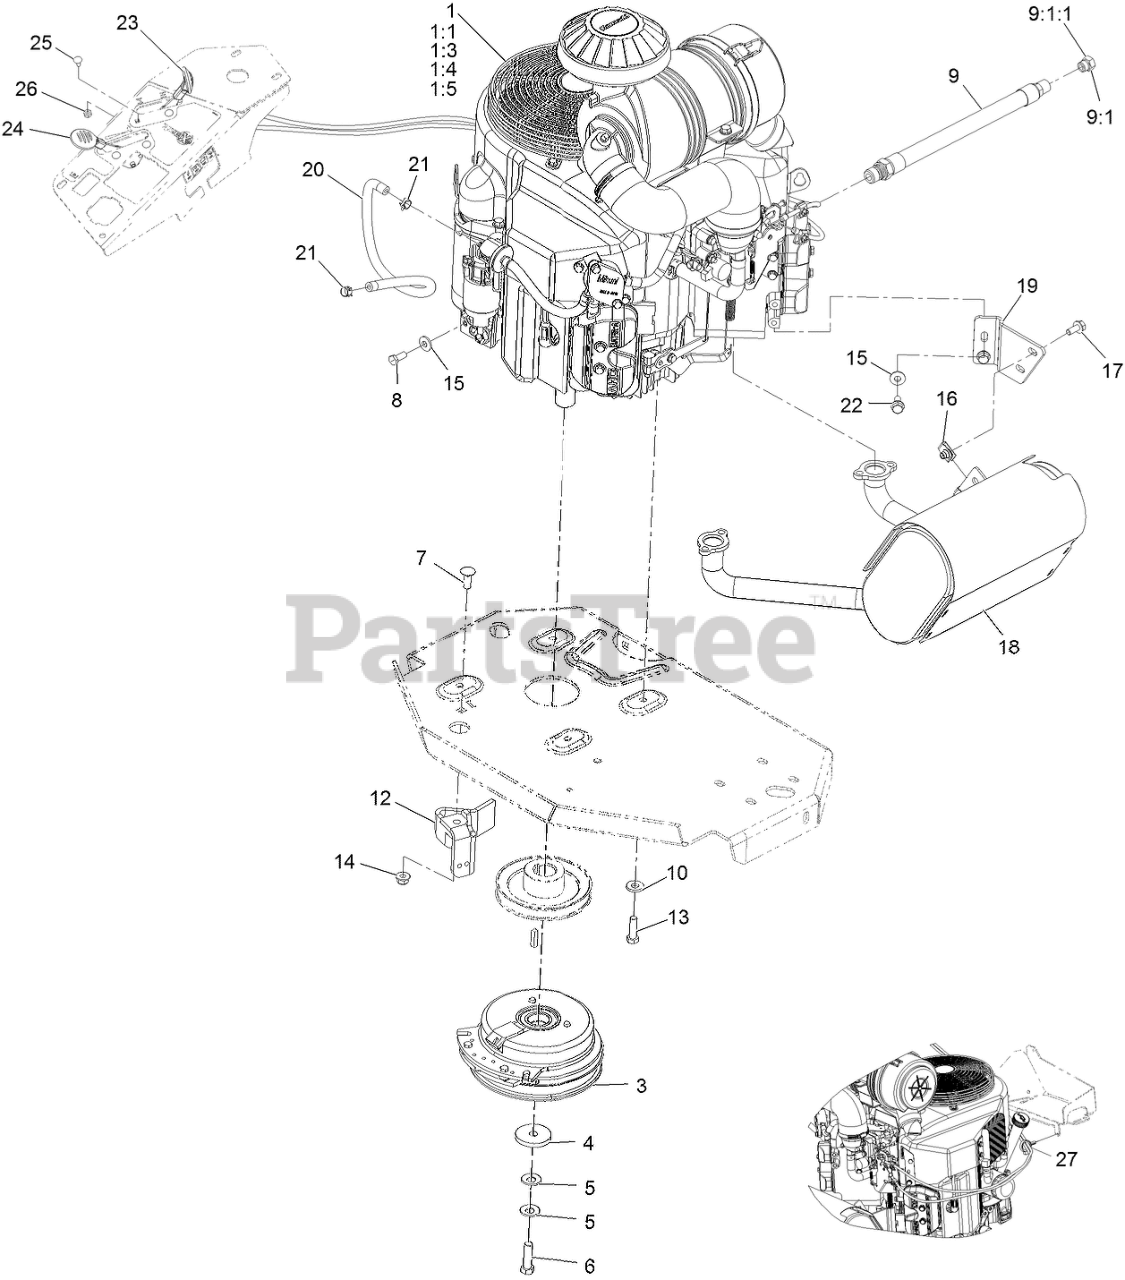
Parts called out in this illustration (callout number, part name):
1:1	Engine Oil Filter
1:3	Kawasaki 49019-0031 Fuel Filter
1:4	Kawasaki 11013-7039 Safety Filter
1:5	Kawasaki 11013-7038 Air Filter
3	CLUTCH KIT
4	WASHER-CLUTCH
5	WASHER-SPRING
6	SCREW-HH 7/16-20 X 1 1/2 W/LOCTITE
7	SCREW-CARR
8	SCREW-HH
9	ENGINE OIL DRAIN HOSE ASM
9:1	PLUG-HH
9:1:1	O-RING
10	WASHER-BELLEVILLE
12	CLUTCH-ANCHOR
13	SCREW-HH
14	NUT-HF, NI
15	WASHER-SPRING
17	SCREW-HHF
18	MUFFLER
19	BRACKET-MUFFLER
20	HOSE-FUEL
21	CLAMP-HOSE
22	SCREW-HHF
23	ASM, CHOKE CABLE
24	ASM,THROTTLE CABLE
25	BOLT-CARR
26	NUT-LOCK, NI
27	CLAMP-HOSE
